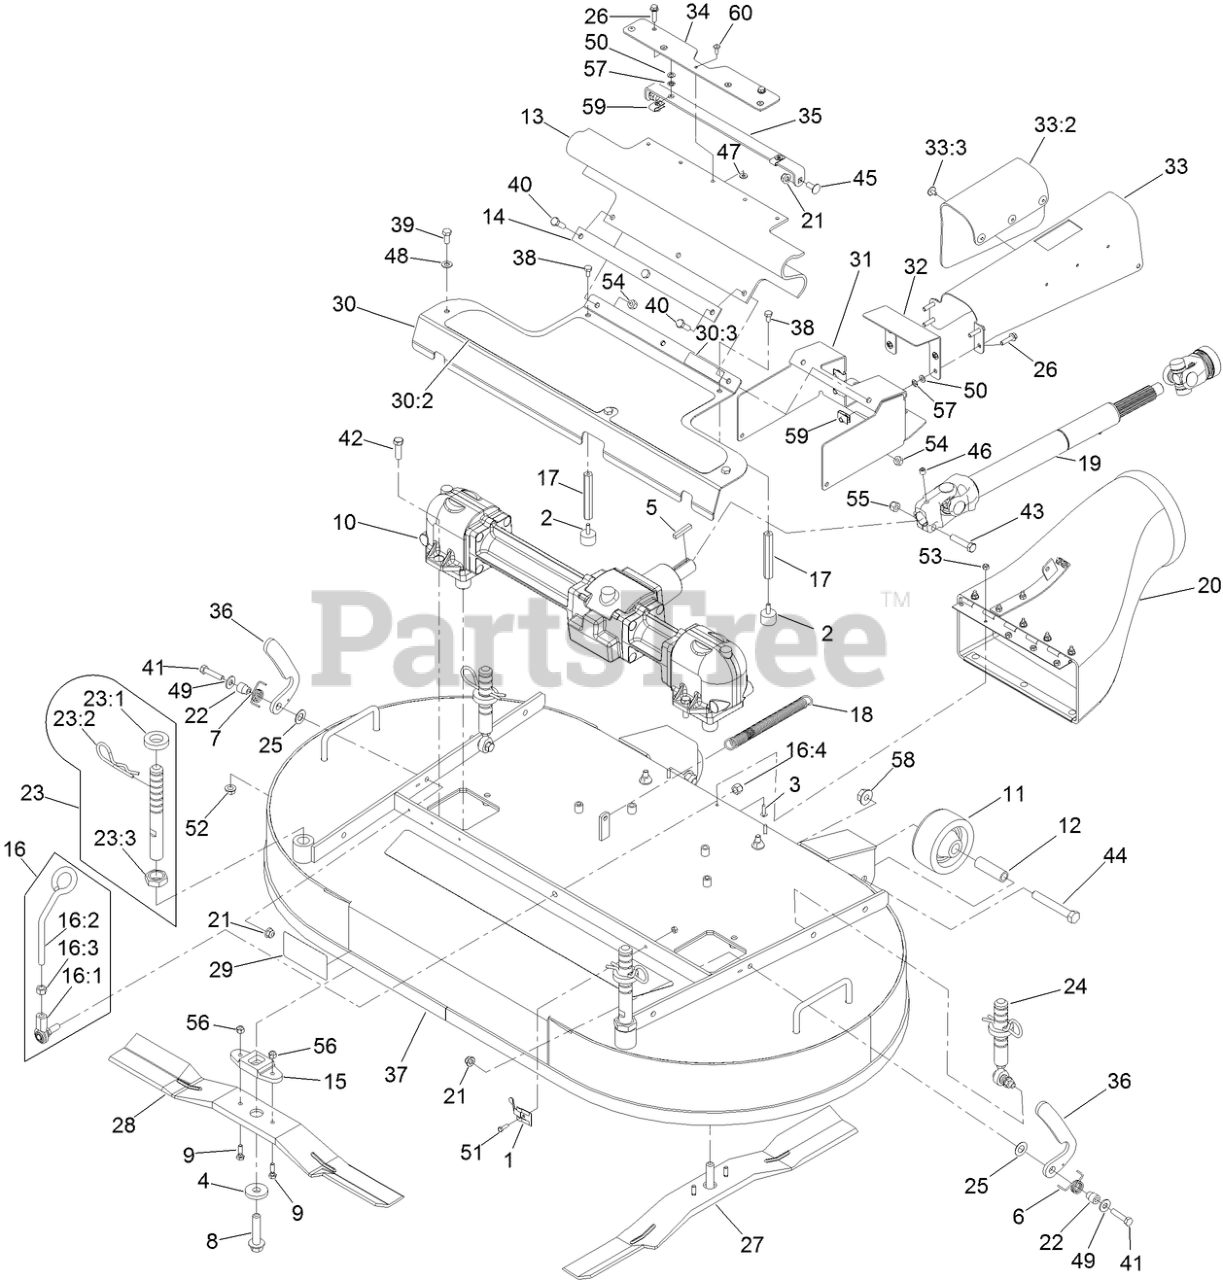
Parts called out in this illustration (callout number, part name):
1	CLIP-DECK, HOLD UP ROD
2	BUMPER
3	SCREW-HEAD, TRUSS
4	WASHER
5	KEY-SQUARE
6	SPRING-TORSION, LH (YELLOW)
7	SPRING-TORSION, RH
8	BOLT-BLADE
9	BOLT-SHEAR
10	GEAR BOX ASM
11	ROLLER-DECK
12	SPACER-ROLLER
13	GUARD-PTO
14	STRAP-DRIVE, LINE COVER
15	DRIVER-BLADE
16	DECK LATCH ASM
16:1	BALLJOINT-RH
16:2	LATCH-DECK
16:3	NUT-HEX
16:4	NUT-LOCK
17	STAND-OFF
18	SPRING-EXTENSION
19	DRIVE SHAFT ASM
20	DISCHARGE TUBE ASM
21	NUT-HF, NI
22	COLLAR-BASKET
23	FRONT DECK HEIGHT ADJUST ASM
23:1	SPACER-DECK SUPPORT
23:2	PIN-CUT HEIGHT
23:3	NUT-JAM
24	REAR DECK HEIGHT ADJUST ASM
25	WASHER-PLASTIC
26	SCREW-HHF
27	BLADE-25IN, LH
28	BLADE-25IN, RH
30	GEARBOX COVER ASM
30:2	PAD-ANTI SKID
30:3	DECAL-DANGER
31	GUARD-PTO, FRONT
32	GUARD-PTO
33	PTO GUARD ASM
33:2	FLAP-RUBBER
33:3	RIVET-POP
34	PLATE-GUARD
35	MOUNT-GUARD
36	LATCH - DECK
37	DECK-CUTTING 48 W/DECALS
38	SCREW-HH
39	SCREW-HH
40	SCREW-HH
41	SCREW-HH
42	SCREW-HH
43	SCREW-HH
44	SCREW-HH
45	SCREW-CARR
46	SCREW-SET, HSH
47	WASHER-FLAT
48	WASHER-PLAIN
49	WASHER-FLAT
50	WASHER-FLAT
52	NUT-HHF, WHIZ
53	NUT-LOCK, NI
54	NUT-LOCK, NI
55	NUT-LOCK, NI
56	NUT-LOCK, NI
57	PUSHNUT-RETAINER, BOLT
58	NUT-HHF
60	RIVET-BLIND
